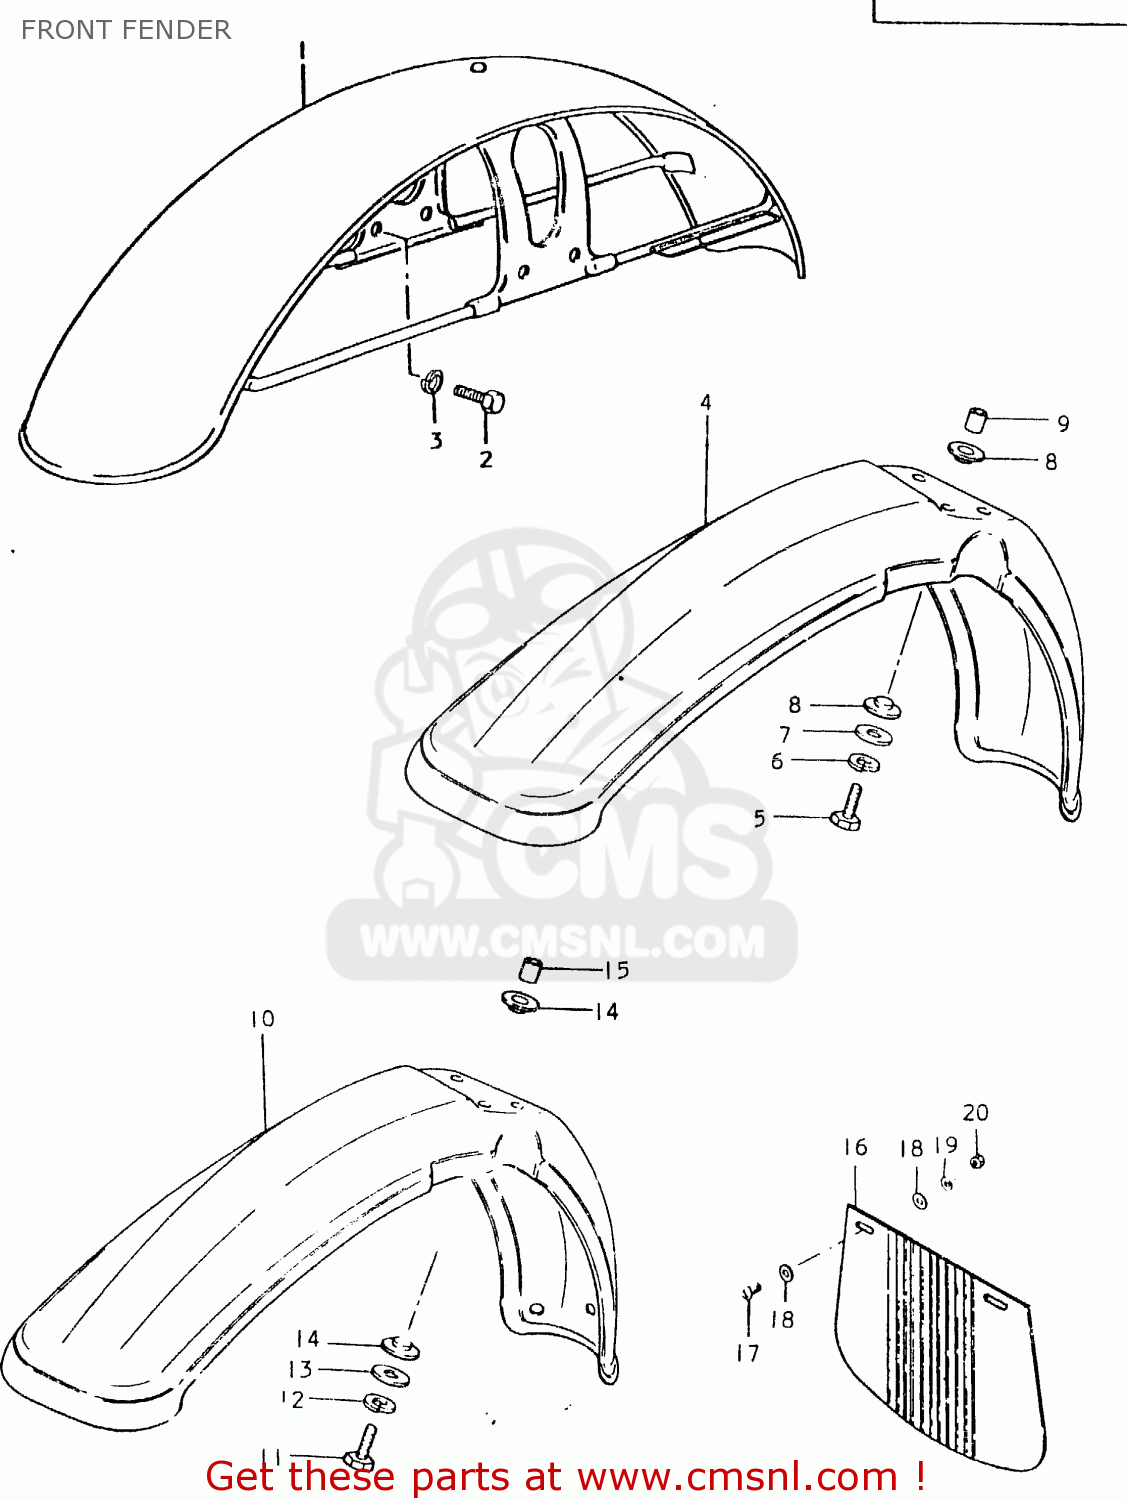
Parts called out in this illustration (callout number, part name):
1	FENDER,FR
2	BOLT
3	LOCK WASHER
4	FENDER,FR
5	BOLT
6	LOCK WASHER
7	WASHER
8	SPACER
9	SPACER
10	FENDER, FRONT (RED)
11	BOLT
12	LOCK WASHER
13	WASHER
14	SPACER
15	SPACER
16	MUD FLAP
17	SCREW
18	WASHER
19	LOCK WASHER
20	NUT
